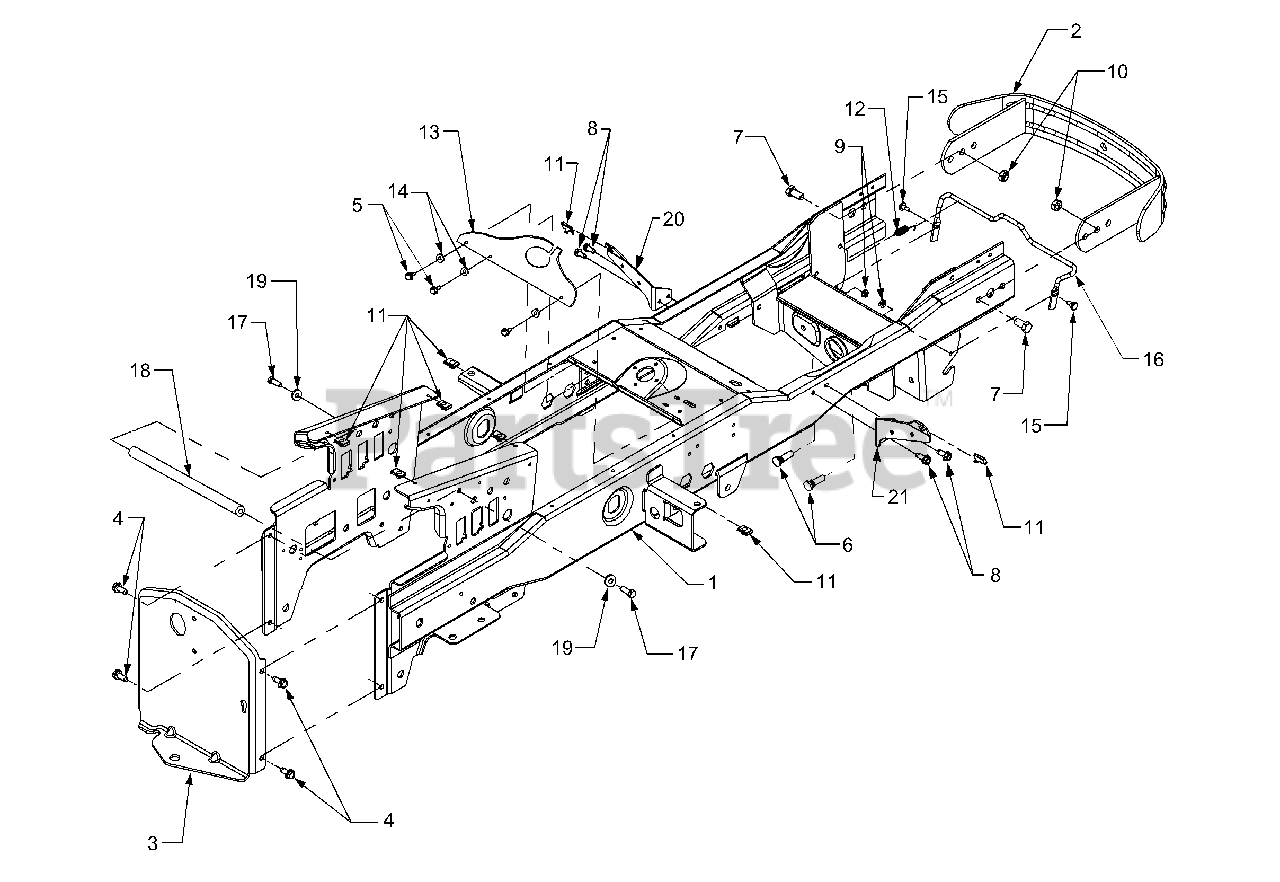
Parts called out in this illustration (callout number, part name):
1	Frame Assembly
2	Bumper, Front
4	Screw, Hex Wash. Hd. Tapp 3/8-16 x .75
5	Screw, Hex Wash. Hd. Tapp 1/4-20 x .5
6	Screw, Round Hd., 3/8-24
7	Screw, Hex Cap 1/2-13 x 1.0 GR5
8	Screw, Hex Wash. Hd. Tapp 5/16-18 x .75
9	Nut, Hex Flange Lock, 1/4-20
10	Nut, Hex Lock, 1/2-13
11	Speed Nut, U-Type, 5/16-18
12	Spring, Extension
13	Flap, Intk.
14	Washer, Flat, .283 x .75 x .030
15	Shoulder Screw, .312 x .18
16	Rod, Front Latch
17	Screw, Hex Cap, 5/16-18 x .875
18	Shaft, Frame Brace
19	Washer, Flat, .344 x .75 x .12
20	Bracket, Running Board LH
21	Bracket, Running Board RH
